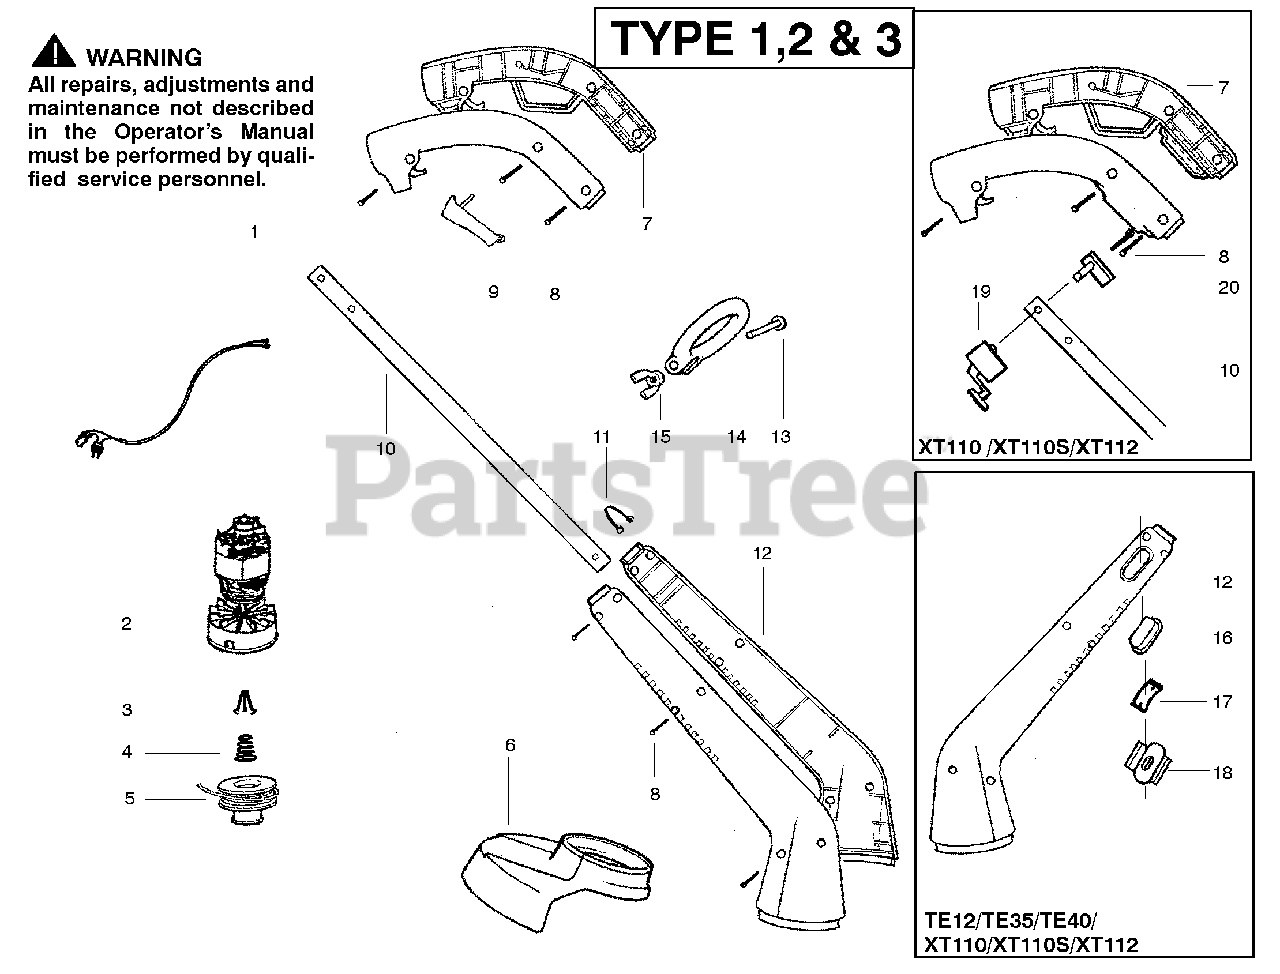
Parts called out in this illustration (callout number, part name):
1	Assy-Wire Harness SG10/12, XT110/112 TE12, TE35
2	Motor/Hub Ass'y TE35/XT110S
3	Retainer-Spool
4	Spring-Return
5	Spool w/ Line
6	Shield w/Limiter SG10/TE35
7	Handle Set SG10/SG12/TE12/ TE35/TE40
9	Trigger Switch
11	Snap Button
12	Housing Set SG10/SG12 TE12/TE35/TE40
14	Assist Handle SG10/SG12/TE12/ TE35/TE40
15	Wing Nut
17	Spring-Button Return TE12/TE35/TE40 XT110/XT110S/XT112
